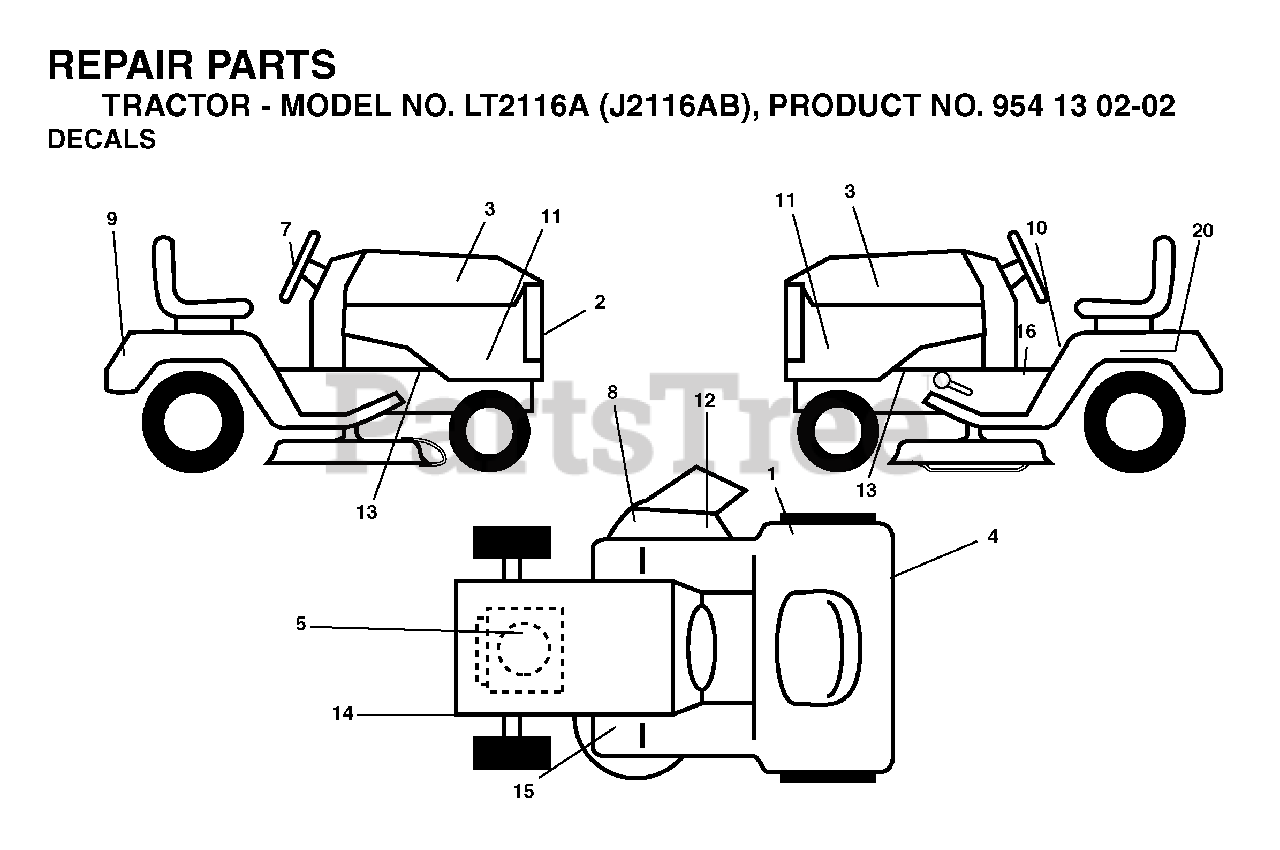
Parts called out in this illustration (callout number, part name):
8	DECAL.INTERNATIONL.CUTFINGER
10	DECAL READ OWNER'S MAN SYMS
12	DECAL DECK "B" 42"
14	DECAL V BELT SCHEMATIC
16	DECAL PARK BRAKE
20	DECAL BTRY SYMBOLS
